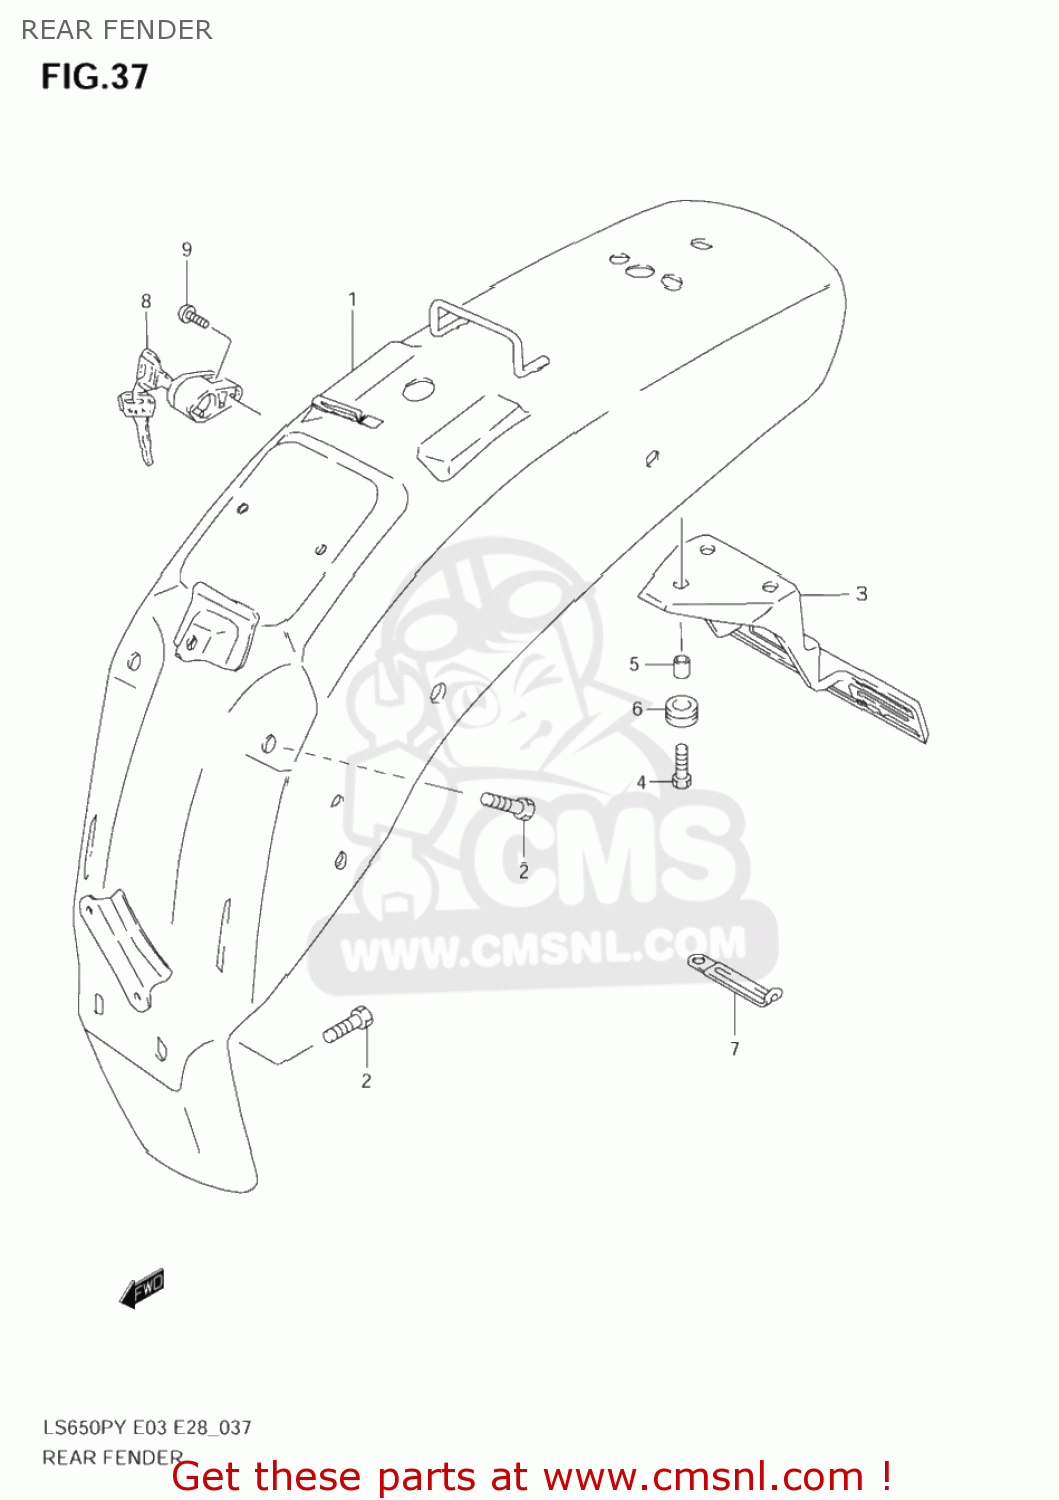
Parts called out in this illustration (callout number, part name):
1	FENDER COMP,REAR
2	BOLT 8X25
3	BRACKET,LICENSE PLATE
4	BOLT(6X20)
5	SPACER(6.5X9X9)
6	CUSHION
7	CLAMP(L:45)
8	LOCK SET,HELMET
9	SCREW
